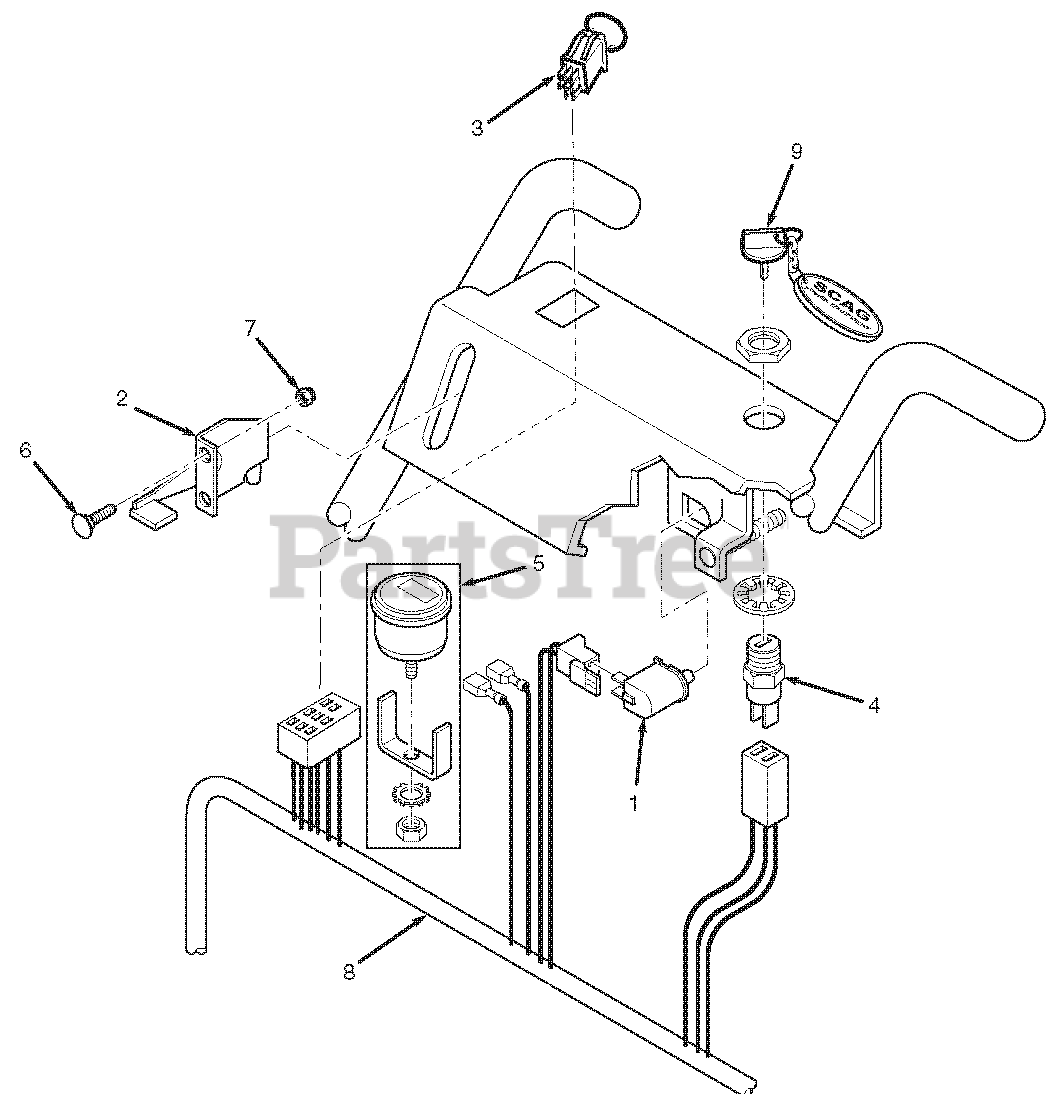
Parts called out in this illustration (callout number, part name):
1	Switch, Neutral Lock
2	Throttle Control - Kawasaki
3	Engagement Switch, Electric Clutch
4	Key Switch
5	Hour Meter (dealer installed)
6	Bolt, Carriage #10-32 x 1/2"
7	Nut, #10-32 Elastic Stop
8	Handle Wire Harness, Manual Start
9	Key Chain w/Keys
9	Key w/Shroud
